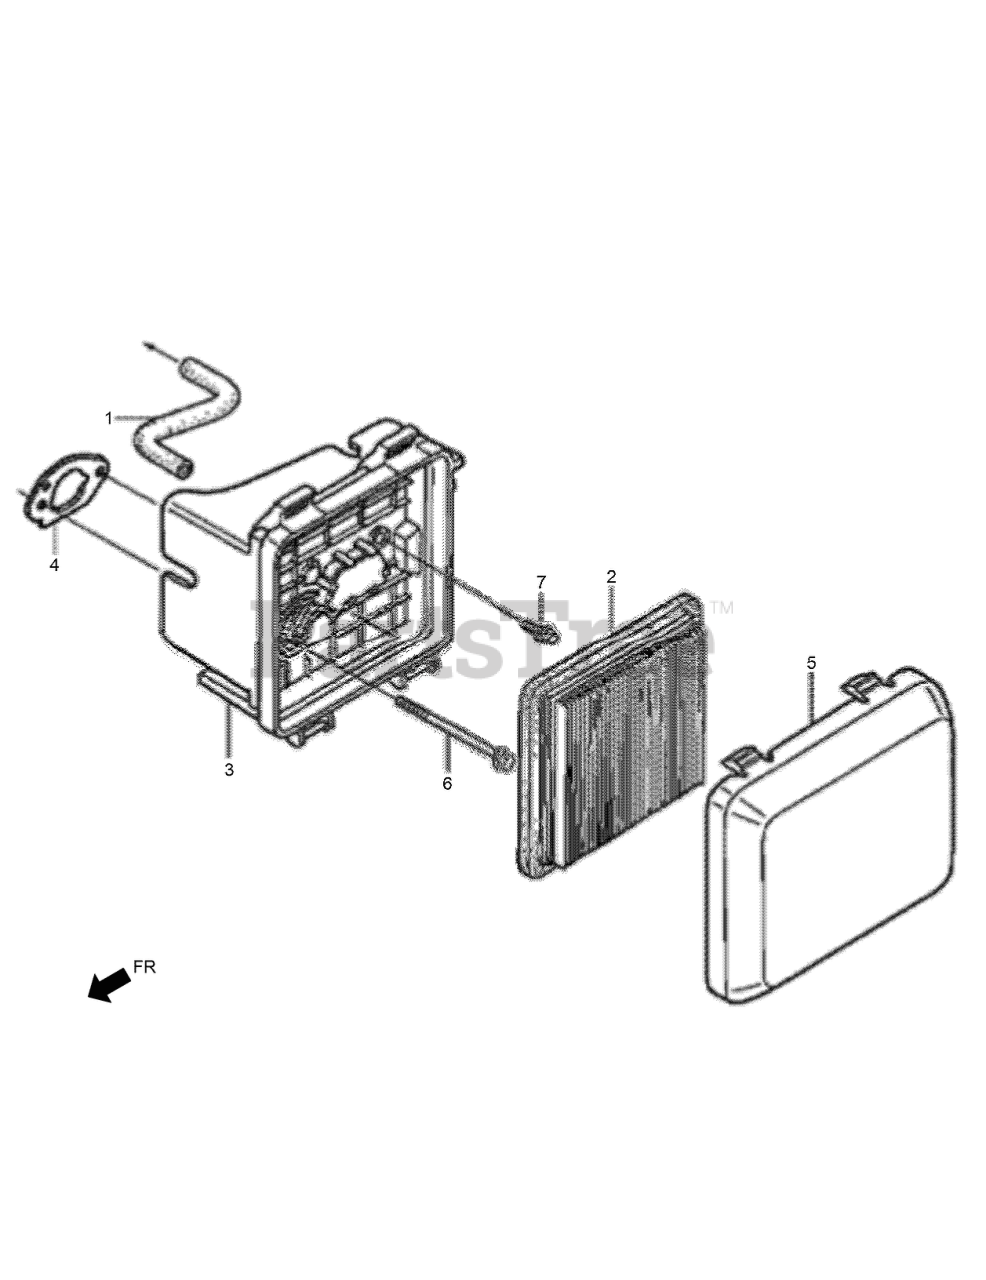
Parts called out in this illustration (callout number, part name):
1	TUBE-BREATHER (to S/N 4363608)
1	TUBE-BREATHER (from S/N 4363609)
2	ELEMENT-AIR CLEANER
3	CASE ASM-AIR CLEANER (to S/N 2933836)
3	CASE ASM-AIR CLEANER (from S/N 2933837 to 4012836)
3	CASE ASM-AIR CLEANER (from S/N 2933837)
4	PACKING-AIR CLEANER
5	COVER-AIR CLEANER (to S/N 3176270)
5	COVER-AIR CLEANER (from S/N 3176271)
6	BOLT-FLANGE-6X86 (to S/N 2937994)
6	BOLT-FLANGE-6X85 (from S/N 2937995)
7	BOLT-FLANGE-6X14 (to S/N 2933836)
